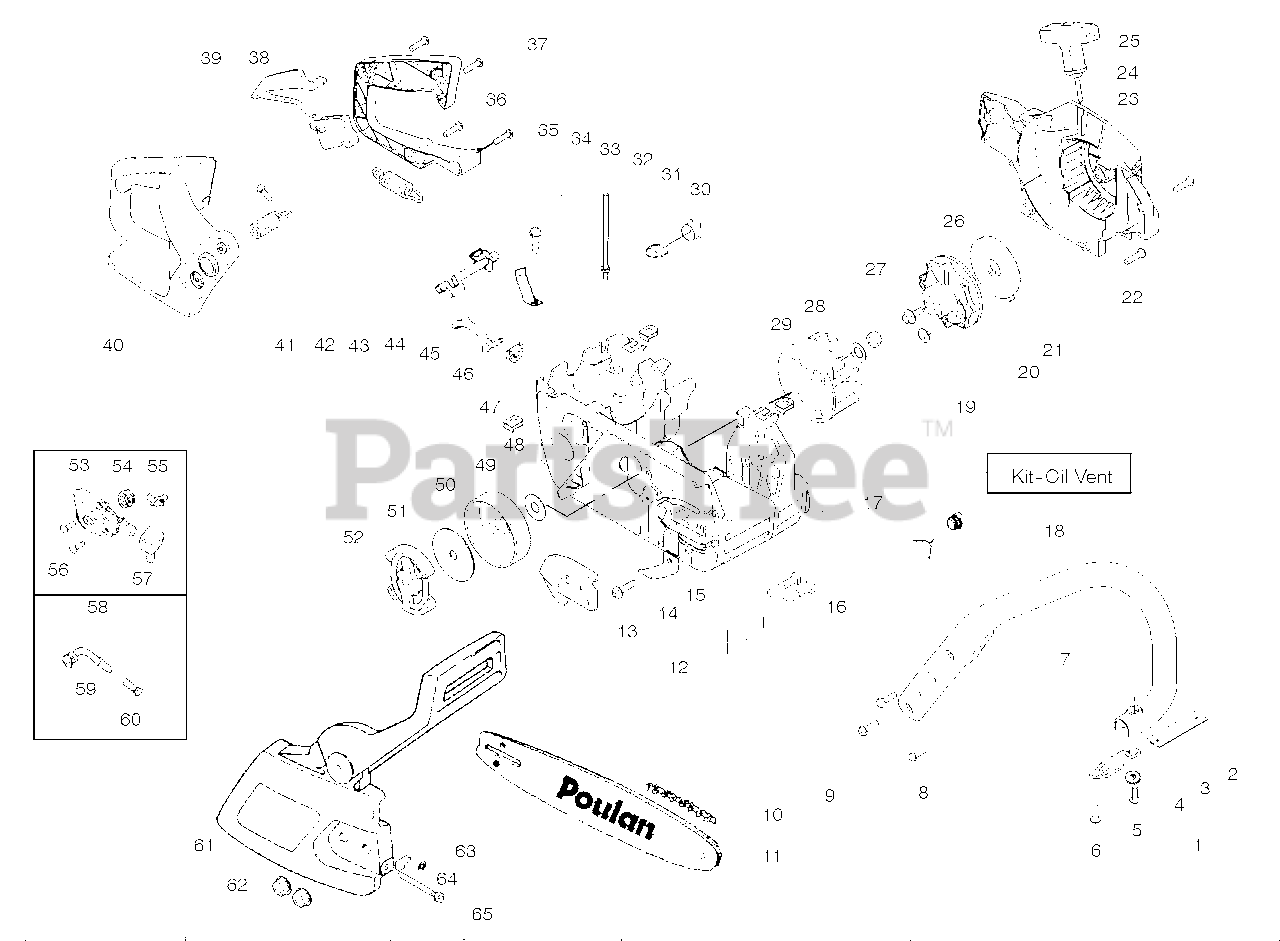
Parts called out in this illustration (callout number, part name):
1	Assy.-Isolator
2	Limiter Strap
3	Spring-Isolator
4	Washer
7	Front Handle
10	Chain - 18"
11	Bar - 18"
13	Plate-Bar Mount.
15	Chain Catcher
16	Bolt-Bar
17	Assy-Oil Cap
18	Kit-Oil Vent
19	Nut-Flywheel
21	Starter Pulley
23	Housing-Fan
24	Kit - Rope
25	Handle-Starter
26	Spring-Recoil
28	Washer-Flywheel
29	Assy-Flywheel
30	Assy-Fuel Cap
31	Fitting-fuel line
32	Kit-Fuel line (large)
33	Spring-Switch
35	Cover-Rear Handle
38	Throttle Lockout
39	Trigger-Throttle
40	Handle - Rear
41	Kit-Isolator (Upper)
43	Spring-Isolator
44	Lever-Switch
45	Lever-Choke
46	Grommet-Knob
47	Nut-"U"-Type
48	Assy-Chassis fuel lines and caps
49	Washer-Thrust
50	Assy.-Clutch Drum w/bearing
51	Washer-Clutch
52	Assy. Clutch
53	Kit - Oil Pump
54	Gear-Worm Spring
55	Elbow-Oil Pickup
57	Seal Block
58	Assy-Oil Pick-up
59	Pick-up Oiler
60	Filter-Oil
61	Assy.-Chain Brake
62	Nut-Bar Mounting
63	Pin-Bar Adjust
64	Retainer
65	Kit-Bar Adjusting
